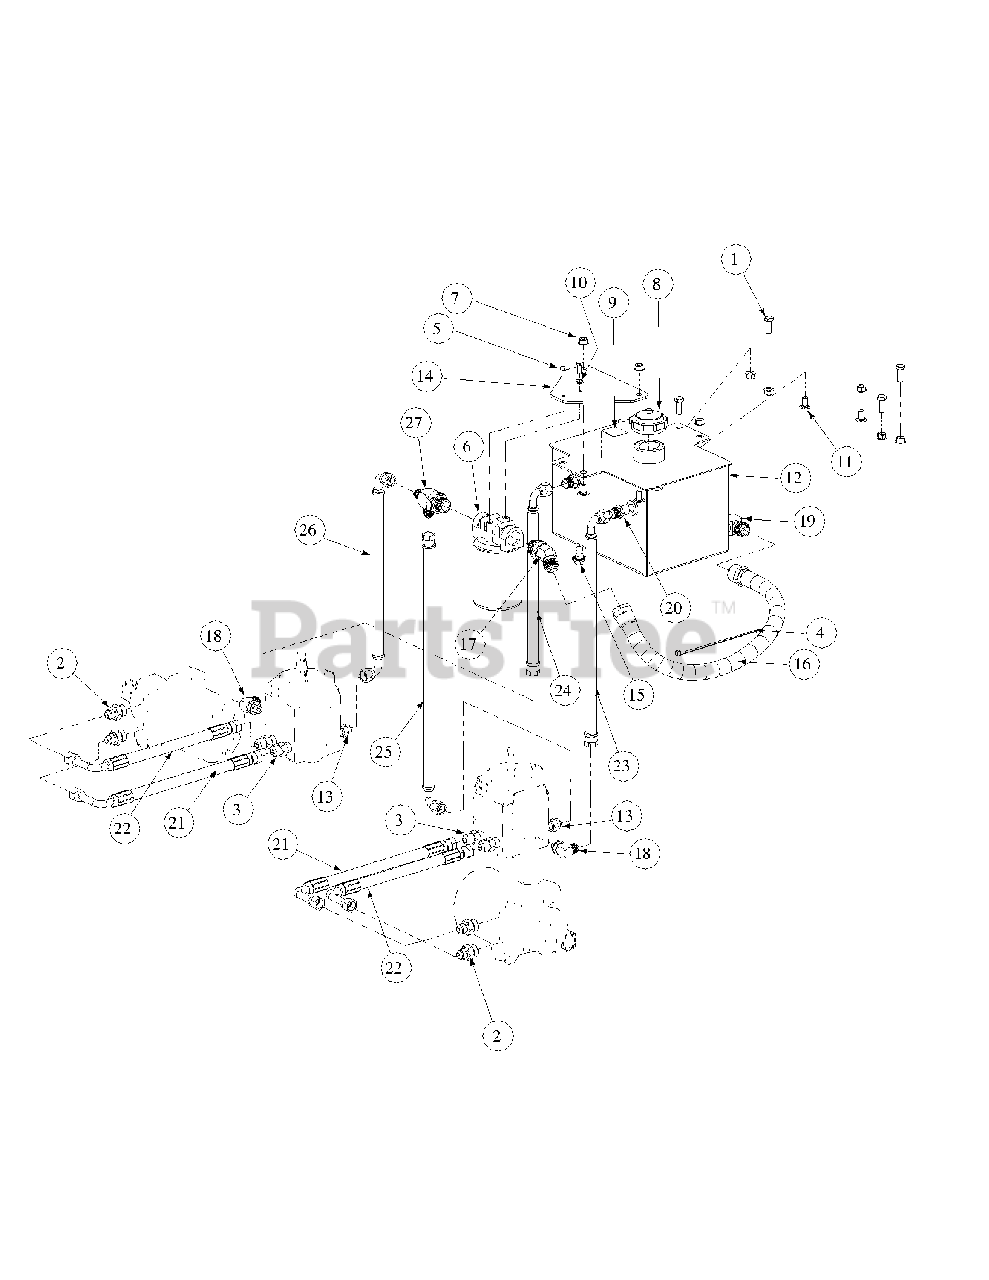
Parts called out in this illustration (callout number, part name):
1	Hex Cap Screw, 3/8-16, 1
2	Fitting 1/2 x 3/4 - O Ring
3	Fitting 1/2 x 1/2 - O Ring to Flare
4	Cable Tie, 3/16 x .05 x 7.4
5	Hex Cap Screw, 1/4-20, .75
6	Filter Head 3/4
7	Hex Nut Flange Lock, 3/8-16
8	Cap, Hydro Oil Tank
9	Decal Oil Only 20W50
10	Lock Washer, 1/4
11	Carriage Bolt, 3/8-16 x .75 LG.
12	Hydraulic Tank Assembly
13	Fitting Connector, 1/2 x 3/8
14	Oil Filter Mounting Plate
15	Oil Pan Drain Plug w/ Seal
16	Tank to Filter Hose Assembly
17	Fitting, 3/4 x3/4 x 45 degree
18	Elbow Fitting, 3/8 O-ring, 1/2 Flare
19	Fitting Elbow, 1/2 x 1/2
20	Fitting, 3/8 NPT, 1/2 Flare
21	Long Pressure Hose Assembly
22	Short Pressure Hose Assembly
23	17.75" Return Hose Assembly, RH
24	14.25" Return Hose Assembly, LH
25	21.25" Supply Hose Assembly, RH
26	15.50" Supply Hose Assembly, LH
27	Tee Fitting, 3/4 x 1/2 x 1/2
